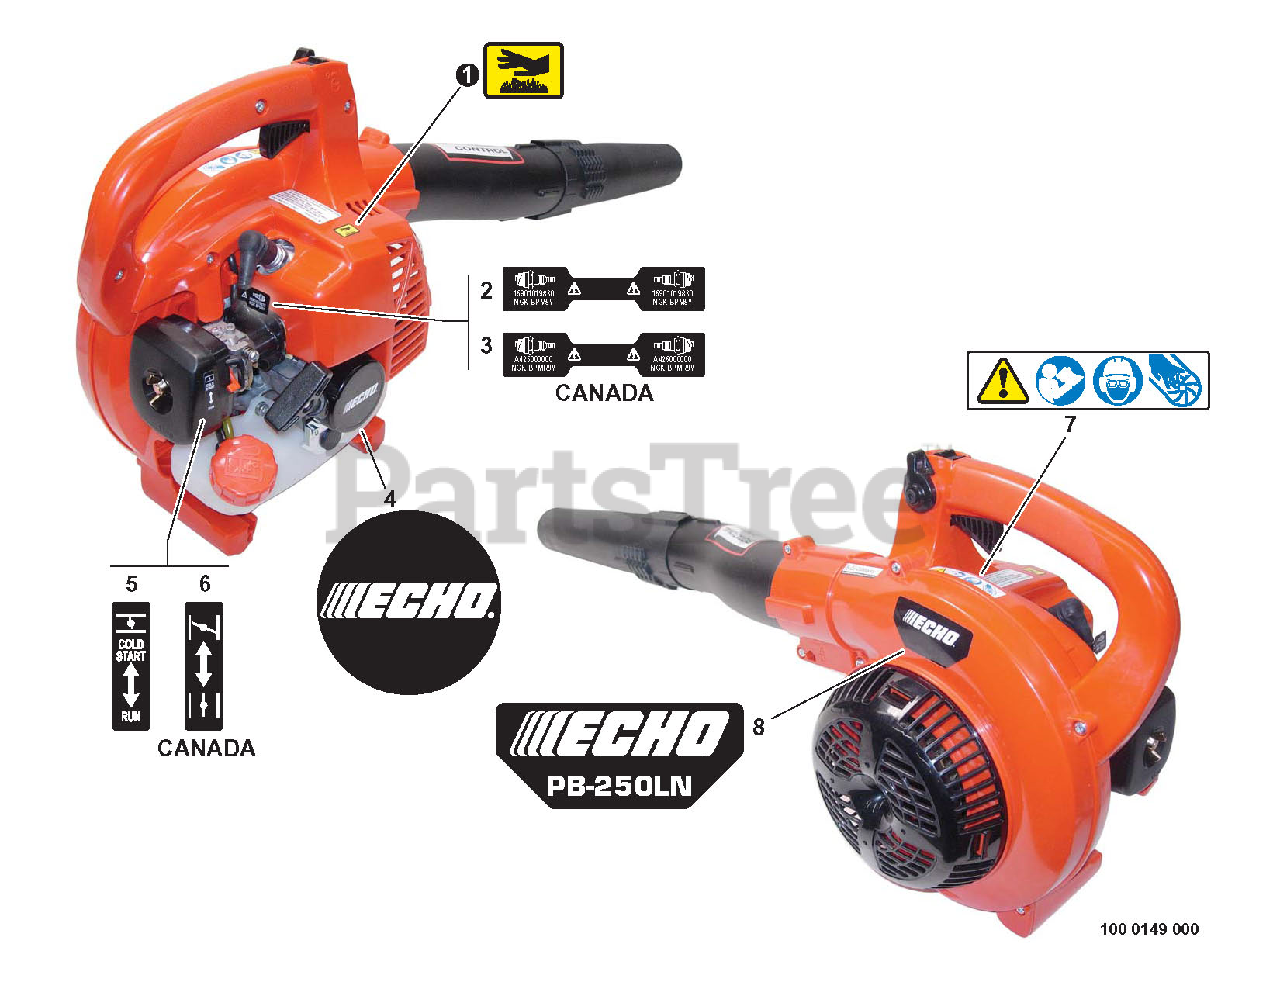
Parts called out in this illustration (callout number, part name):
1	LABEL - HOT SURFACE
2	LABEL - SPARK PLUG -- BPM-8Y
3	LABEL - SPARK PLUG -- BPMR-8Y
4	LABEL - ECHO
5	LABEL - CHOKE
6	LABEL - CHOKE
7	LABEL - CAUTION
8	LABEL - MODEL PB-250LN
